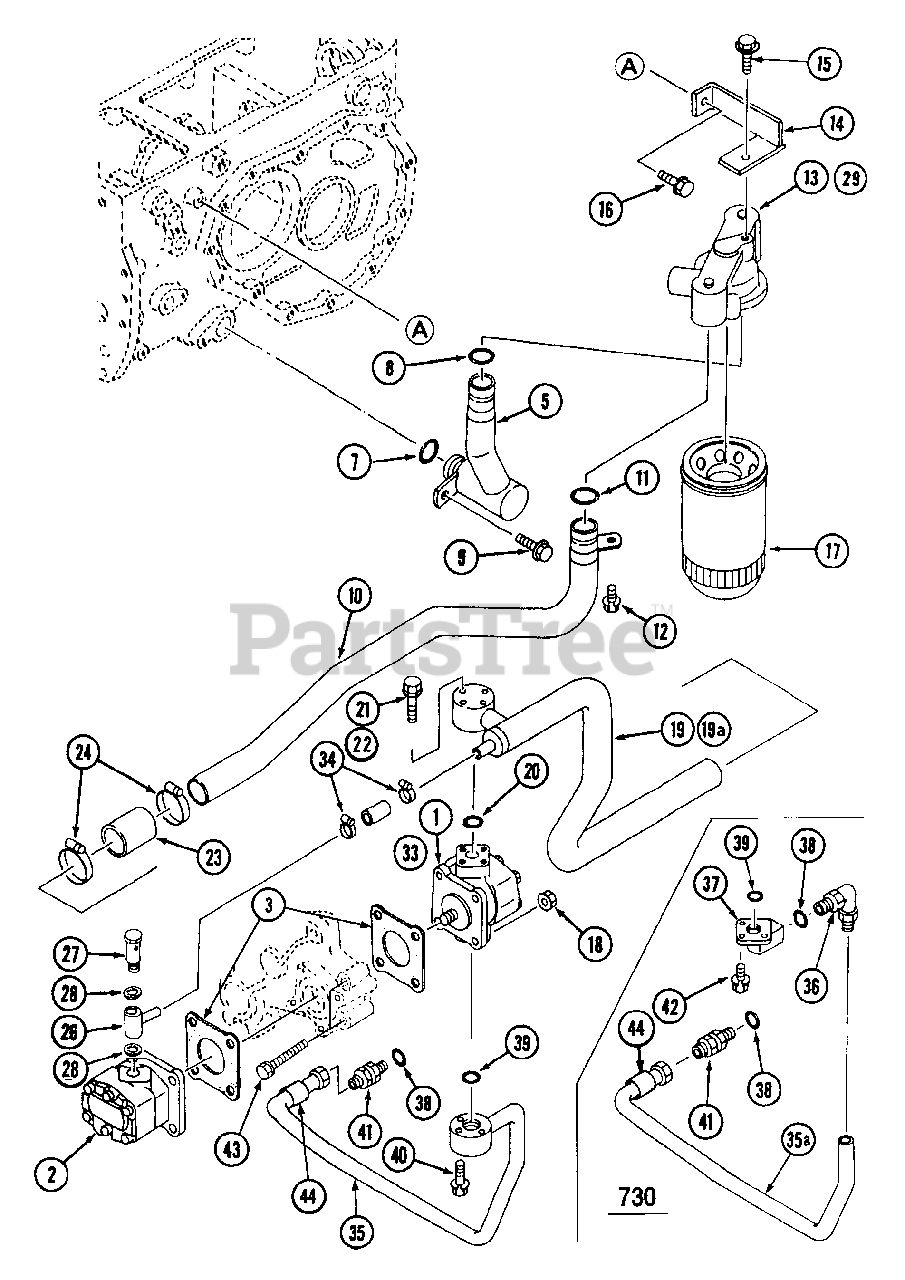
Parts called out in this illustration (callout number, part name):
5	Pipe A, Suction
10	Pipe B, Suction
13	Base, Filter
19	Pipe C, Suction
19A	Pipe D, Suction
21	Bolt
35	Pipe A, Press.Ass'y.
35A	Pipe B, Press.Ass'y.
36	Body (Elbow)
37	Joint
41	Body (Nipple)
42	Bolt
44	Pipe
